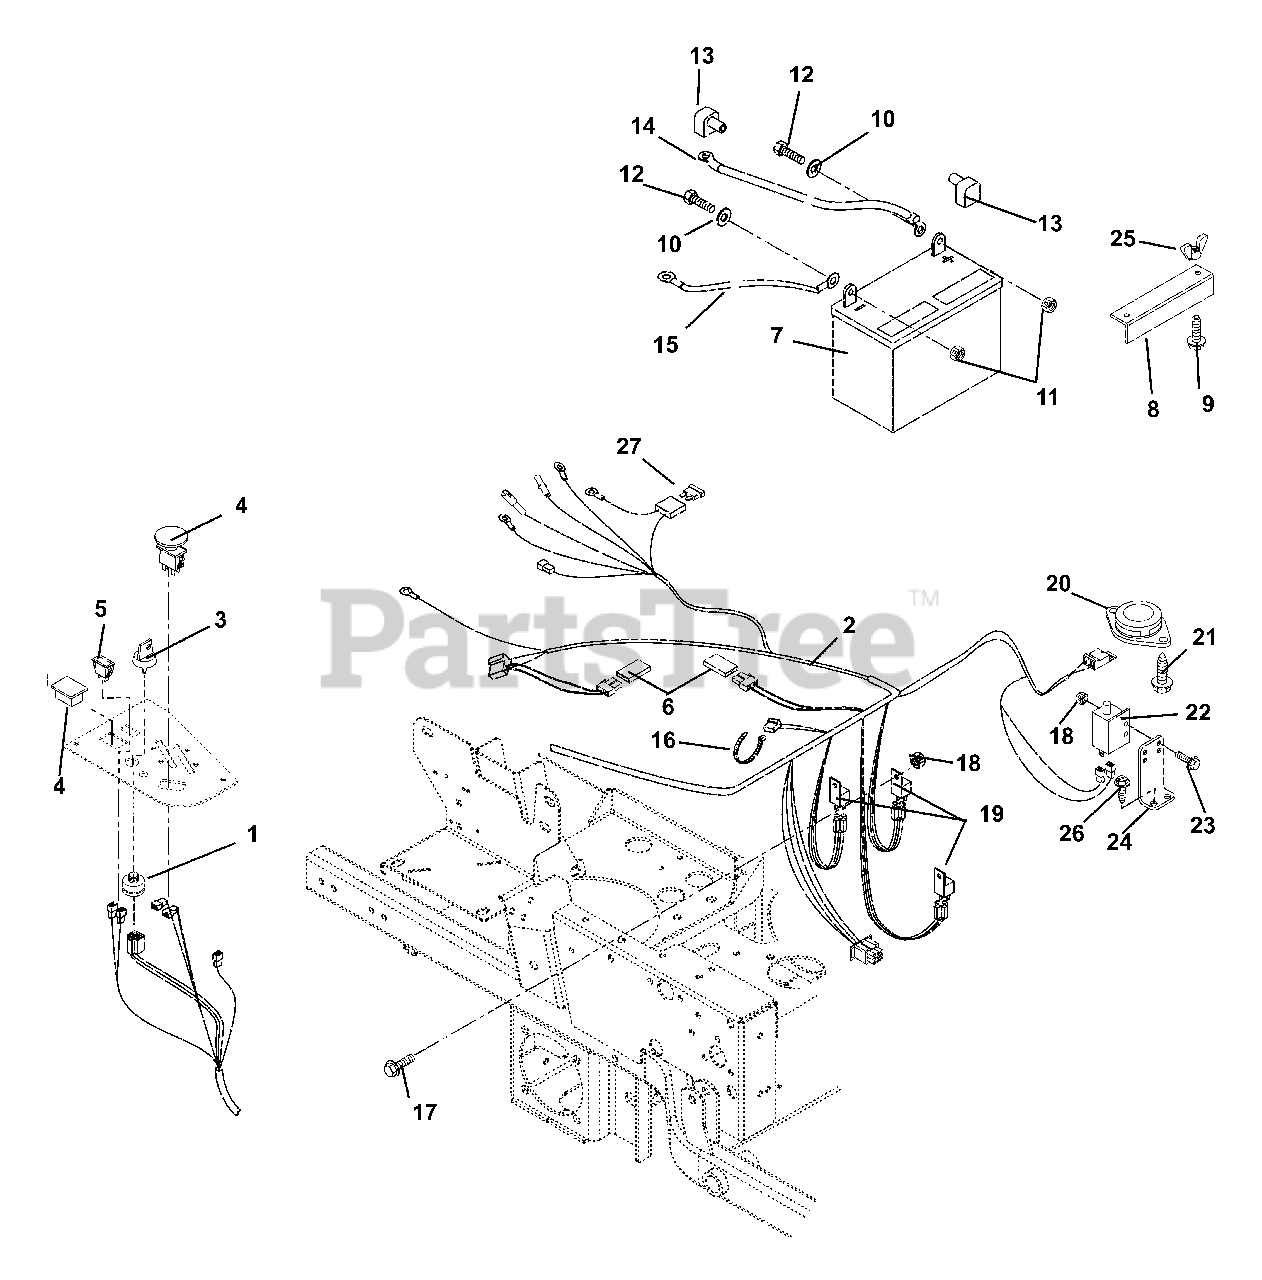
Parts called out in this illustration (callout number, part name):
1	SWITCH, IGNITION
2	HARNESS, IZ & MONST. EYE-Q
3	KEY, W/ SHIELD
4	SWITCH, CLUTCH
5	LIGHT,INDICATOR
6	DIODE, CONNECTOR SHELL
7	BATTERY, 300 CCA 10U1L
8	HOLD DOWN
9	BLT-RDHDSQNK .25-20X7.50 GR2YZ
10	@WSHR-FL-STL.281X.62X.065 YWZC
11	@NUT-LK-TOP-FLG .25-20 YWZC
12	@BLT-HEX .25-20X.75 GR5 YWZC
13	INSULATOR
14	CABLE, POSITIVE BATTERY 26.00
15	CABLE, NEGATIVE BATTERY 24.00
16	CABLE TIE LG 5-1/2
17	@SCR-MCH 10-24X.50 HWH YWZC
18	@NUT-LK-NYL 10-24 W/INSRT YWZC
19	RELAY
20	SEAT SWITCH
21	@SCR-TAP 12-24X.50 HWH TR YWZC
22	SWITCH- SINGLE POLE N.O.
23	@SCR-MCH 10-24X.75 HWH YWZC
24	BRAKE SWITCH MOUNT - BLACK
25	NUT-LK WING .250-20 YWZC
26	@SCR-TAP .25-20X.50 HWH TR YWZ
27	FUSE, 30 AMP.
28	HOURMETER-QUARTZ 80VDCMAX
